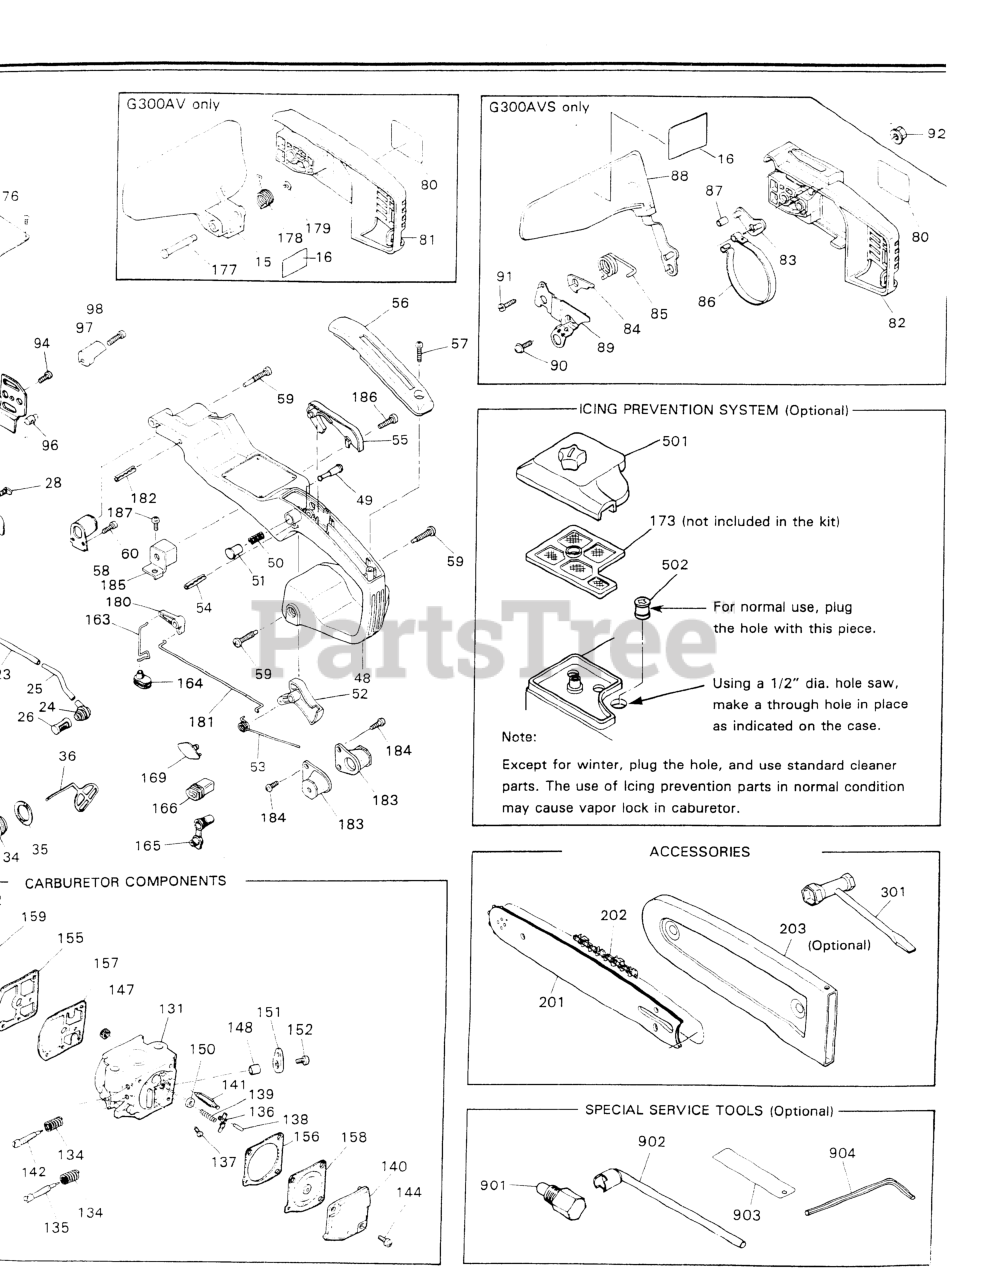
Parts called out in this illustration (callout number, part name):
23	PIPE (USE -85411)
24	GROMMET (RPLS -31320)
28	PIN
35	GASKET
48	HANDLE (NLA)
49	STOPPER
51	KNOB
53	SPRING
56	COVER (NLA)
57	SCREW
60	SCREW (REPLACES 50030272)
81	COVER, CHAIN
92	NUT
94	SCREW
96	NUT
97	CATCHER, CHAIN (USE -53412)
134	SPRING (NLA)
137	SCREW (NLA)
141	VALVE (NLA)
144	SCREW (USE -81351)
147	STRAINER (NLA)
151	LEVER
155	KIT, GASKET
156	KIT, GASKET
157	KIT, DIAPHRAGM
158	KIT, DIAPHRAGM
159	KIT, DIAPHRAGM
164	GROMMET
165	GROMMET A
169	CAP
179	RING, SNAP, M4
183	JOINT (C)
185	JOINT (D)
186	SCREW, M5 X 12
201	BAR 14
203	PROTECTOR (14.5
301	WRENCH, PLUG
902	WRENCH (TOOL)
903	GAUGE (TOOL)
904	WRENCH (TOOL)
NI	PIPE COMP (USE -31202)
NI	PIPE ASSEMBLY
NI	HANDLE (F)
NI	HANDLE (NLA)
NI	KIT, GASKET
NI	ICING KIT
